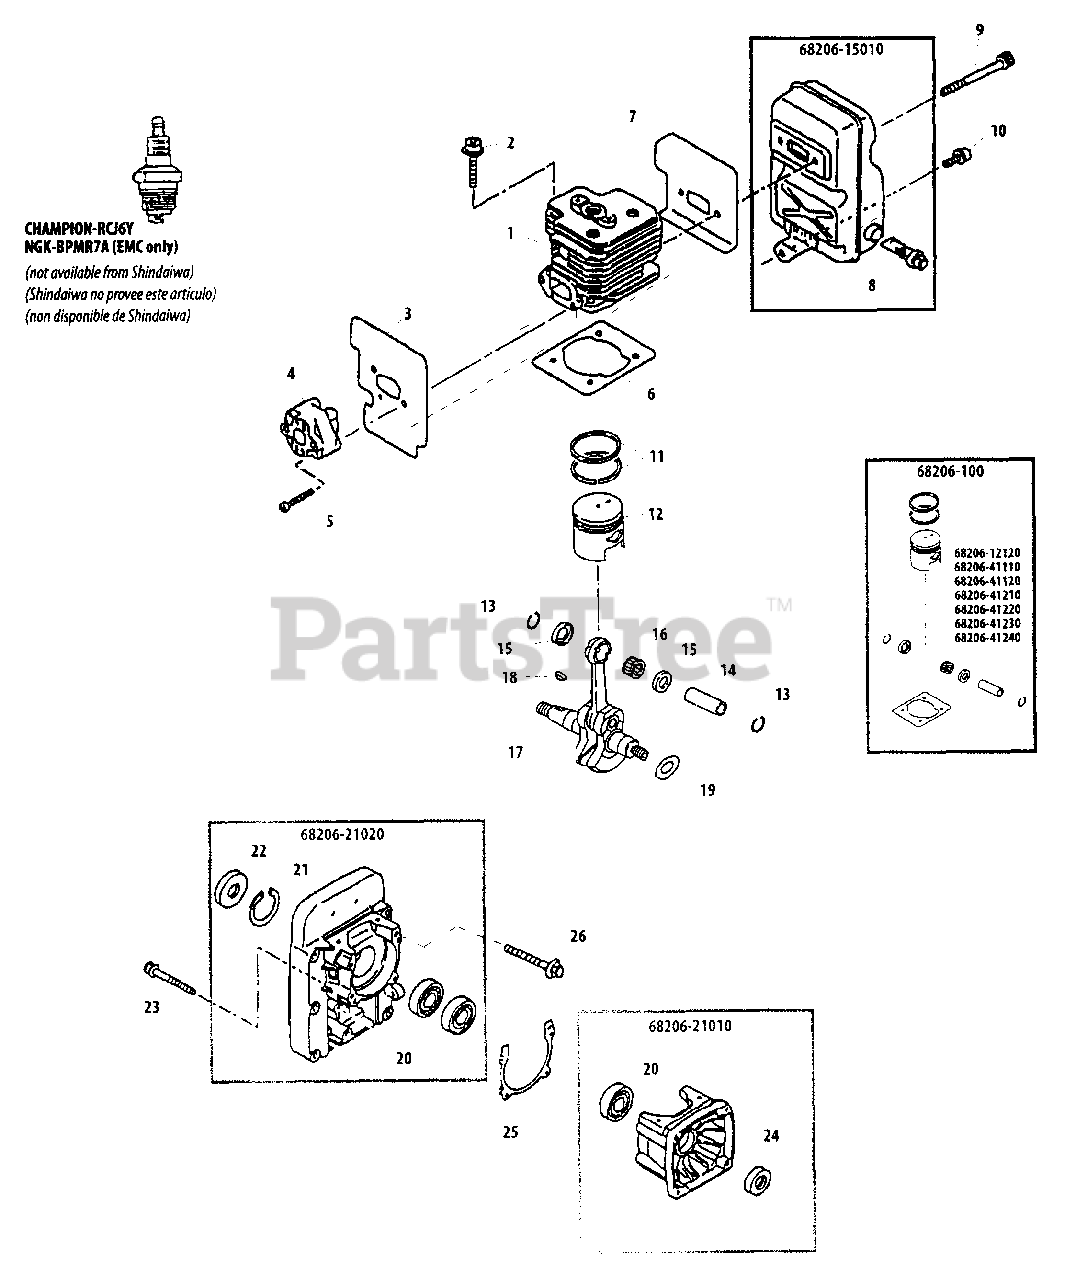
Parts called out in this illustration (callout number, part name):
1	CYLINDER
2	BOLT - 5X22
3	GASKET, INTAKE
4	INSULATOR
5	SCREW - 5X35
6	GASKET, CYLINDER
7	GASKET, EXHAUST
8	SCREEN, SPARK ARRESTOR
9	SCREW - 6X70
10	BOLT - 6X12 -- FLANGE
11	RING, PISTON
12	PISTON
13	RING, RETAINING
14	PIN, PISTON
15	WASHER, THRUST
16	BEARING, NEEDLE
17	CRANKSHAFT ASSY
18	KEY
19	SHIM
20	BEARING, BALL - 6202
21	RING, RETAINING
22	SEAL, OIL
23	SCREW - 5X30
24	SEAL, OIL
25	GASKET
26	SCREW - 6X40
68206-100	PISTON KIT
68206-15010	MUFFLER ASSY
68206-21010	CRANKCASE ASSY - REAR
68206-21020	CRANKCASE ASSY - FRONT
